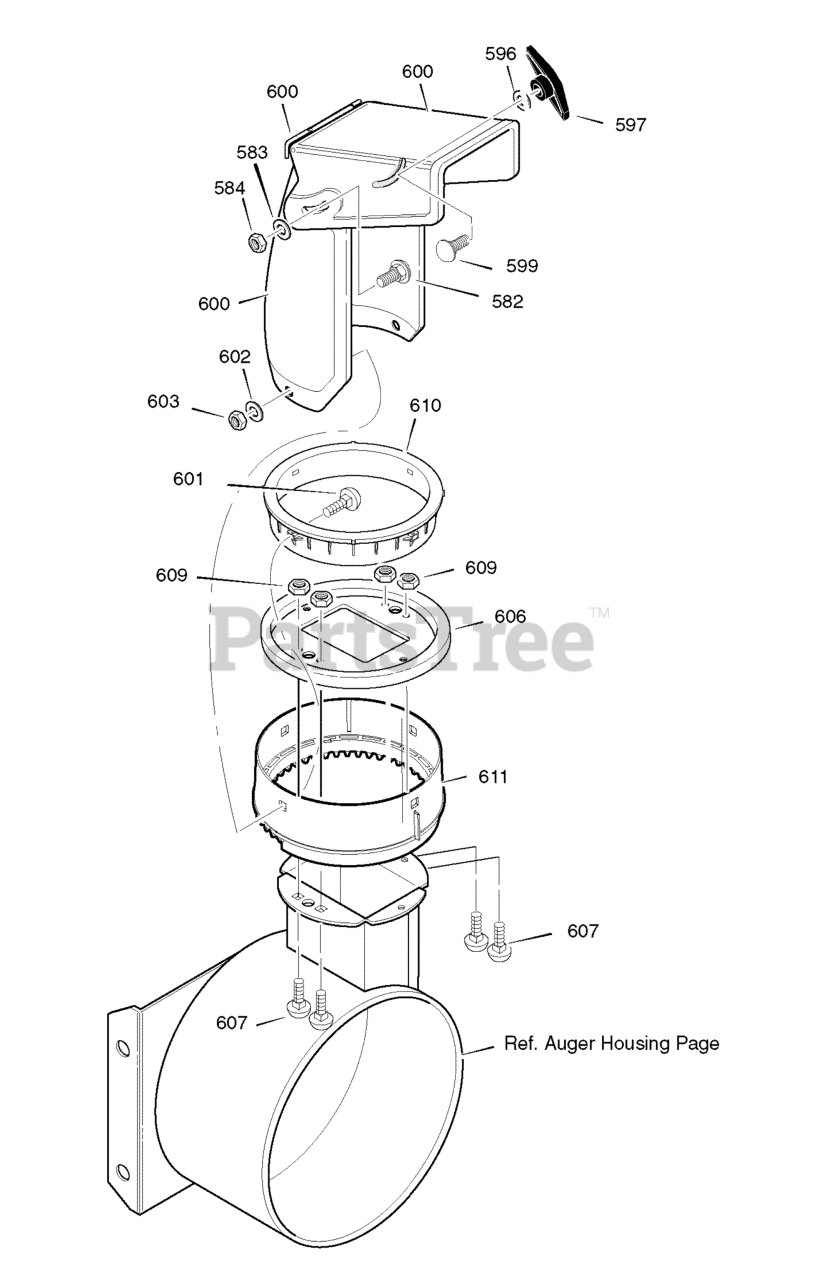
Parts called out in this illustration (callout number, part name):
582	BOLT, 5/16-18 X 1.00 CARG.
583	WASHER, FLAT
584	NUT, 5/16-18 NYLOCK
596	WASHER
597	KNOB, WING 3.00
599	BOLT, 5/16-18X1.125
600	CHUTE ASSEMBLY
601	BOLT
602	WASHER, FLAT
603	NUT, 5/16-18 HEXNYL
606	CHUTE COLLAR
607	SCREW, 1/4-20 X .75
609	NUT, 1/4-20 HEX NYLOCK
610	RETAINER RING INNER
611	RETAINER RING OUTER
